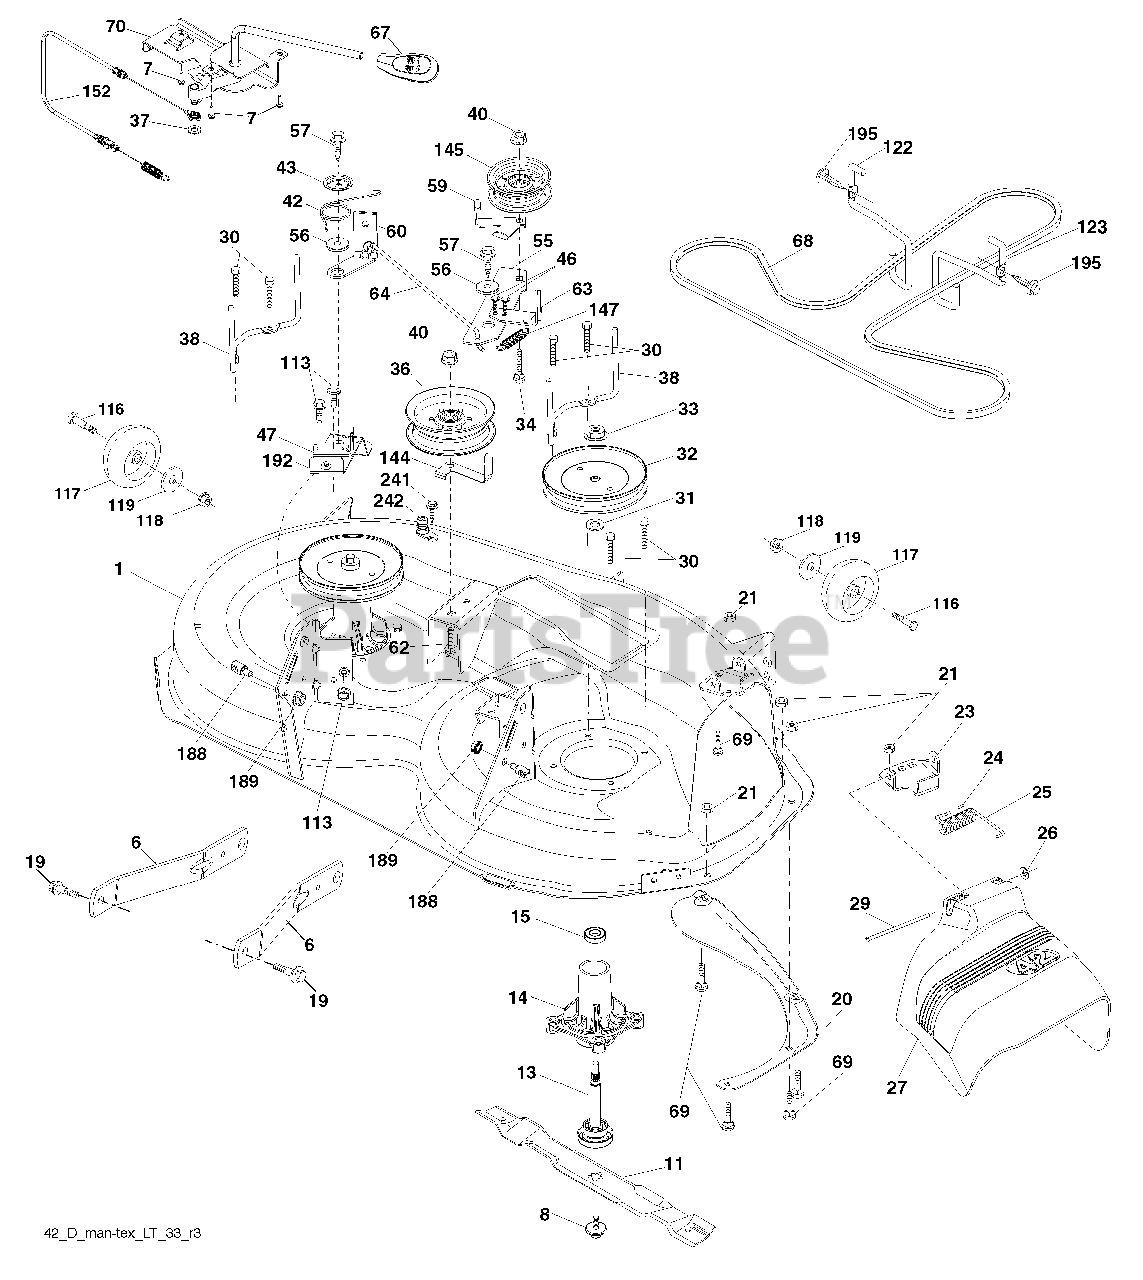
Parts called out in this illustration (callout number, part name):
1	Mower Housing
6	Arm Suspension
7	Screw #10 x .750 BOS Thread
8	Bolt/Washer Asm 7/16-20 unf
11	Blade, 42" Hi-Lift
13	Shaft Assembly, Mandrel
14	Housing, Mandrel
15	Bearing, Ball, Mandrel
19	Bolt, Shoulder
20	Baffle, Vortex
21	Nut, Crownlock 5/16-18 unc
23	Bracket, Deflector
24	Cap, Sleeve
25	Spring, Torsion, Deflector
27	Shield, Deflector
29	Rod, Hinge
30	Screw Thdrol Rolling Wsh Hd
31	Washer, Spacer
32	Pulley, Mandrel
33	Nut, Toplock, Flanged
34	Bolt Carr Sh. 3/8-16 x 1-1/2 Gr. 5
36	Pulley, Idler, Flat
37	Washer
38	Keeper Belt LH Mandrel
40	Nut, Lock Flg. 3/8-16 unc
42	Spring Torsion Brake
43	Spring Torsion Retainer
46	Screw Thd Roll 1/4-20 x 5/8
47	Bracket Clutch Cable
55	Arm, Idler
56	Spacer, Retainer
57	Screw 3/8-16 x 1
59	Guard, Tuv Idler
60	Arm Brake Mower
62	Bolt Rd Hd Sq Nk 3/8-16 unc x 2
63	Arm Brake Mower
64	Link Brake
67	Handle Clutch Cable
68	V-Belt
69	Bolt
70	Clutch Asm Manual
113	Screw 5/16-18
116	Bolt, Shoulder
117	Wheel, Gauge
118	Nut, Crownlock 3/8-1
119	Washer 13/32 x 7/8 x 14 Ga.
122	Keeper Belt Engine LH
123	Keeper Belt Engine RH
144	Keeper Belt
145	Pulley Idler
147	Spring Return
152	Manual Clutch Cable
188	Stud Fastener
189	Nut Lock Hex Flange
192	Bracket Brake Stand LH
195	Screw 3/8-16 x 3/4
241	Screw TT #10-32 5 3/8 Flange
242	Port Washout
